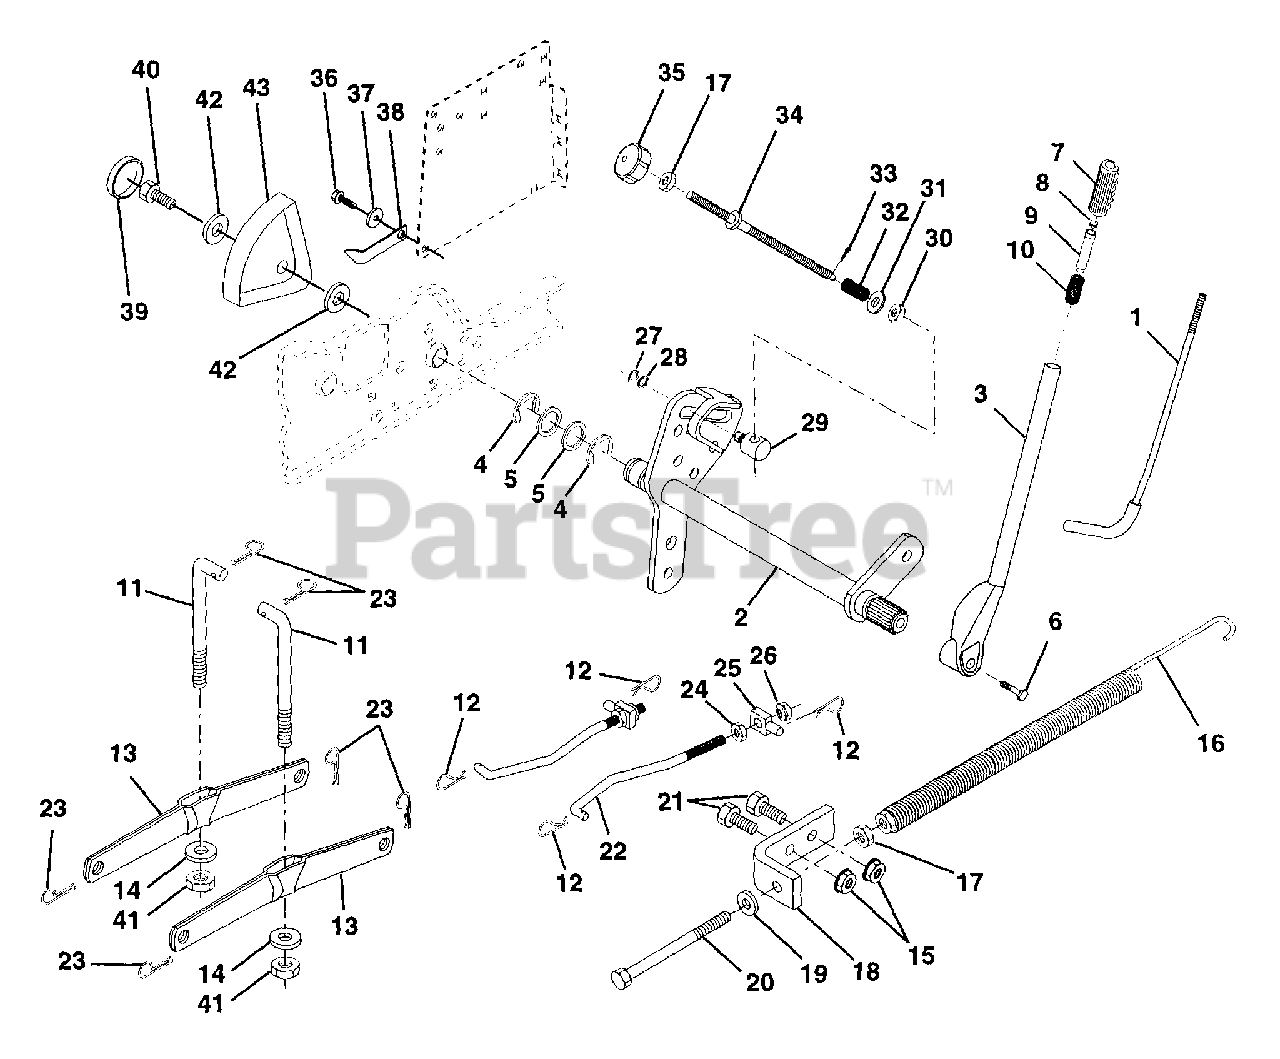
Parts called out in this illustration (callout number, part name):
1	Rod Asm., Lever
2	Shaft Asm., Lift Vgt
3	Lever Asm., Lift Rh
4	E-Ring Truarc #5133-87
5	Washer 29/32 x 1-1/4 x 16 Ga.
6	Bolt, Fin hex 3/8-16 x 1-1/2
7	Grip, Handle Fluted
8	Button, Plunger
9	Plunger, Lever Lift
10	Spring 2-1/8"
11	Link Lift
12	Retainer, Spring
13	Arm, Suspension Vgt
14	Bearing
15	Nut, Crownlock 3/8-16 Unc
16	Spring Asm., Assist Lift
17	Nut, Hex Jam 3/8-16 Unc
18	Bracket, Spring Assist
19	Washer 13/32 x t 3/16 x 16 Ga.
20	Bolt, Adjust Spring Assist
21	Bolt, Fin Hex 3/8-16 x 1
22	Link, Front
23	Retainer, Spring
24	Nut, Jam Hex 1/2-13 Unc
25	Trunnion
26	Nut, Lock W/Wsh 1/2-13 Unc
27	Ring, Klip #T5304-37
28	Washer 15/32 x 3/4 x t 6 Ga.
29	Trunnion, Dp Stop Dbl Thds Plt
30	Nut, Special
31	Washer 13/32 x 5/8 x 16 Ga.
32	Spring, Compression Inf Hgt
33	Pin, Cotter 3/32 x 1/2
34	Rod, Adj Lift
35	Knob, Inf 3/8-16 Unc
36	Screw, Thdrol 3/8-16 x 3/4
37	Washer, Nylon
38	Pointer, Pnt Height Indicator
39	Plug, Hole
40	Screw Thdrol. 5/16-18 x 3/4
41	Nut, Crownlock 3/8-24
42	Washer 11/32 x 1-1/2 x 10 Ga.
43	Scale, Indicator Height
